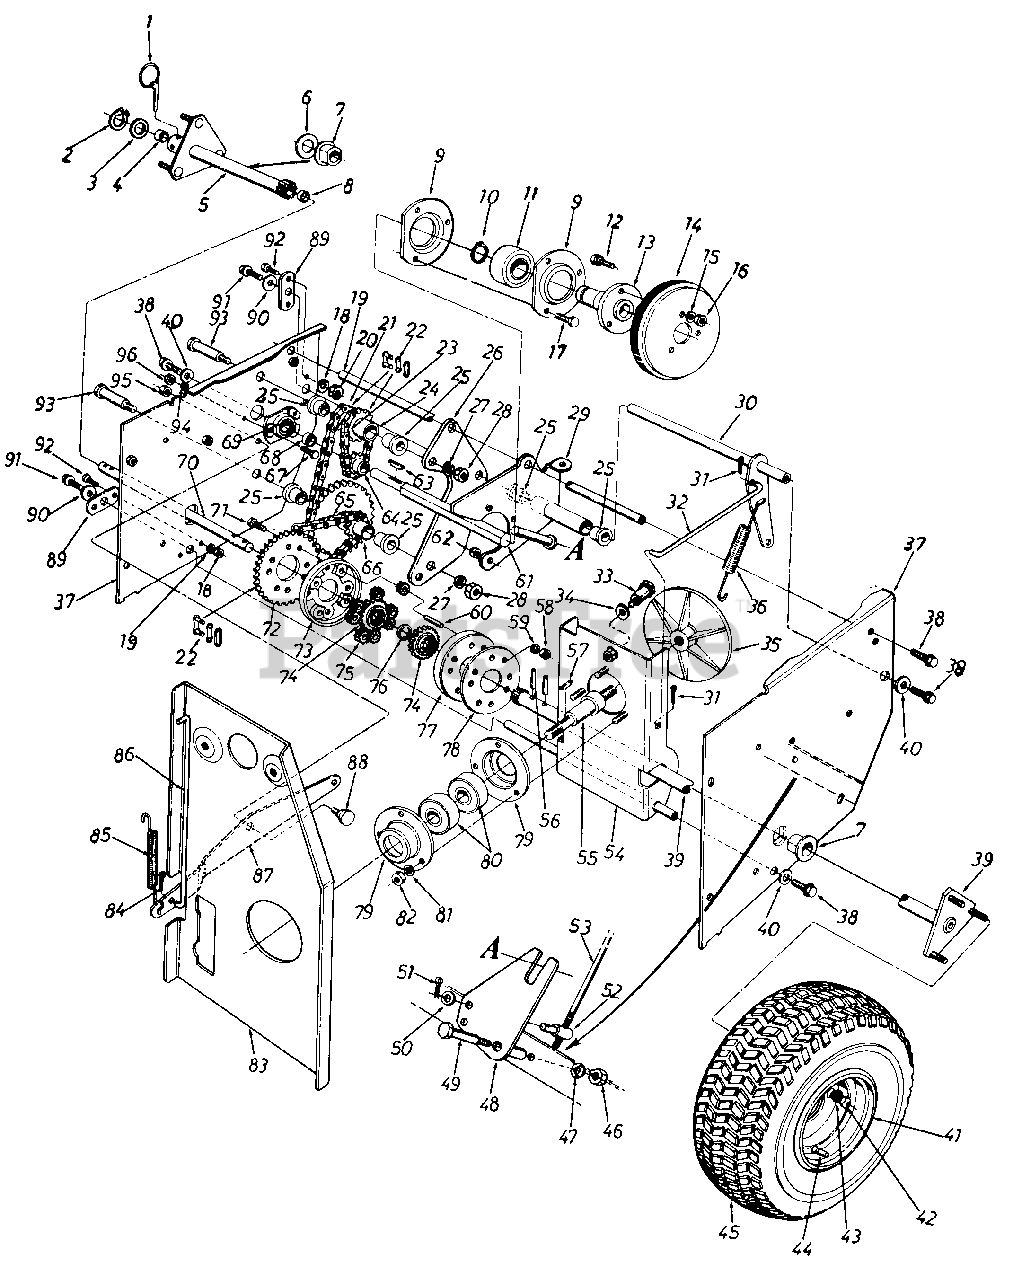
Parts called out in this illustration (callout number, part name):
1	Klick Pin 1/4' Dia. x 1.75"
2	Snap Ring .625" Shaft
3	Fl-Wash. .62" I.D. x 1.25" O.D.
4	Sleeve Brg.
5	Differential Tubing Ass'y. R.H.
6	Fl-Wash. .62" I.D. x 1.25" O.D.
7	Flange Brg. w/Flats 1" I.D.
8	Sleeve Brg.
9	Bearing Housing
10	Snap Ring 1.00" Dia.
11	Ball Brg. .25MM x 52MM x 15MM Thk.
12	Hex Sems Bolt 5/16-18 x .75" Lg.
13	Friction Wheel Adapter
14	Friction Wheel Ass'y.
15	L-Wash. 5/16" I.D.
16	Hex Nut 5/16-18 Thd.
17	Hex Bolt 1/4-28 x .62" Lg.
18	L-Wash. 1/4" I.D.
19	Sliding Support Axle
20	Hex Nut 1/4-20 Thd.
21	#41 Chain 1/2" Pitch x 43 Links
22	Master Link
23	#41 Chain 1/2" Pitch x 19 Links
24	9 and 14 Teeth Sprocket Hub Ass'y.
25	Flange Brg. .630" I.D.
28	Hex L-Jam Nut 3/8-24 Thd.
29	Sliding Brkt. Ass'y.
30	Drive Clutch Brkt. Ass'y.
31	Inter. Cot. Pin 5/16" Dia.
32	Drive Clutch Rod .31" Dia. x 7.38" Lg.
33	Shld. Bolt
34	Bell-Wash. .44" I.D. x .88" O.D.
35	Aluminum Drive Plate
36	Extension Spring .73" O.D. x 4.31 " Lg.
37	Frame Ass'y.
38	Hex L-Bolt 5/16-18 x .62" Lg.
39	Differential Shaft Ass'y.
40	Fl-Wash. .345" I.D. x .75" O.D.
41	Rim Only 16"
42	Cone Nut 3/8-24 Thd.
43	L-Wash. 3/8" I.D. Heavy Duty
44	Tubeless Air Valve
45	Wheel Ass'y. Comp. 16 x 6.5
46	Hex Jam Nut 3/8-16 Thd.
47	L-Wash. 3/8" I.D.
50	Fl-Wash. .344" I.D. x .62" O.D.
51	Cotter Pin 3/32" Dia. x .75" Lg.
52	AdJustment Ferrule
53	Shifting Rod
56	H-Spring Pin Spiral 3/16" Dia. x 1.25" Lg.
57	#61 Hi-Pro Key 3/16 x 5/8" Dia.
58	Hex Nut 1/4-28 Thd.
59	L-Wash. 1/4" I.D.
60	Differential Pin
61	Hex Shaft
62	Hex Ins. Jam L-Nut 1/4-28 Thd.
63	#9 Hi-Pro Key 3/32 x 5/8" Dia.
64	8 Teeth Sprocket
65	Chain .50 Pitch x 37 Links
66	9 and 32 Teeth Sprocket Hub Ass'y.
67	Hex Bolt 1/4-20 x .62" Lg.
68	Spacer .51" I.D. x .69" O.D.
69	Ball Bearing
70	Differential Connecting Shaft
71	Hex Bolt 1/4-28 x 1.75" Lg.
72	28 Teeth Sprocket
73	Differential Housing
74	20 Tooth Spur Gear
75	9 Tooth Spur Gear
76	Fl-Wash. .62" I.D. x 1.25" O.D.
77	Differential Housing
78	Differential Hsg. Support Plate
79	Bearing Housing
80	Ball Brg. .787" I.D. x 1.85" O.D.
81	L-Wash. 5/16" I.D.
82	Hex Nut 5/16-18 Thd.
83	Engine Brkt. Ass'y.
84	Inter. Cotter Pin 5/16" Dia.
85	Extension Spring .38" O.D. x 3.18" Lg.
86	Auger Clutch Rod .31" Dia. x 10.62" Lg.
87	Auger Clutch Brkt.
88	Shld. Bolt .625" Dia. x .170" Lg.
89	Pivot Axle Brkt.
90	Fl-Wash. .345" I.D. x .75" O.D.
91	Hex L-Bolt 5/16-18 x .62" Lg.
92	Hex Bolt 1/4-20 x .62" Lg.
93	Sprocket Hub Tubing 1.880" Lg.
94	L-Wash. 1/4" I.D.
95	Hex Cent. L-Nut 3/8-16 Thd.
96	Hex Nut 1/4-20 Thd.
